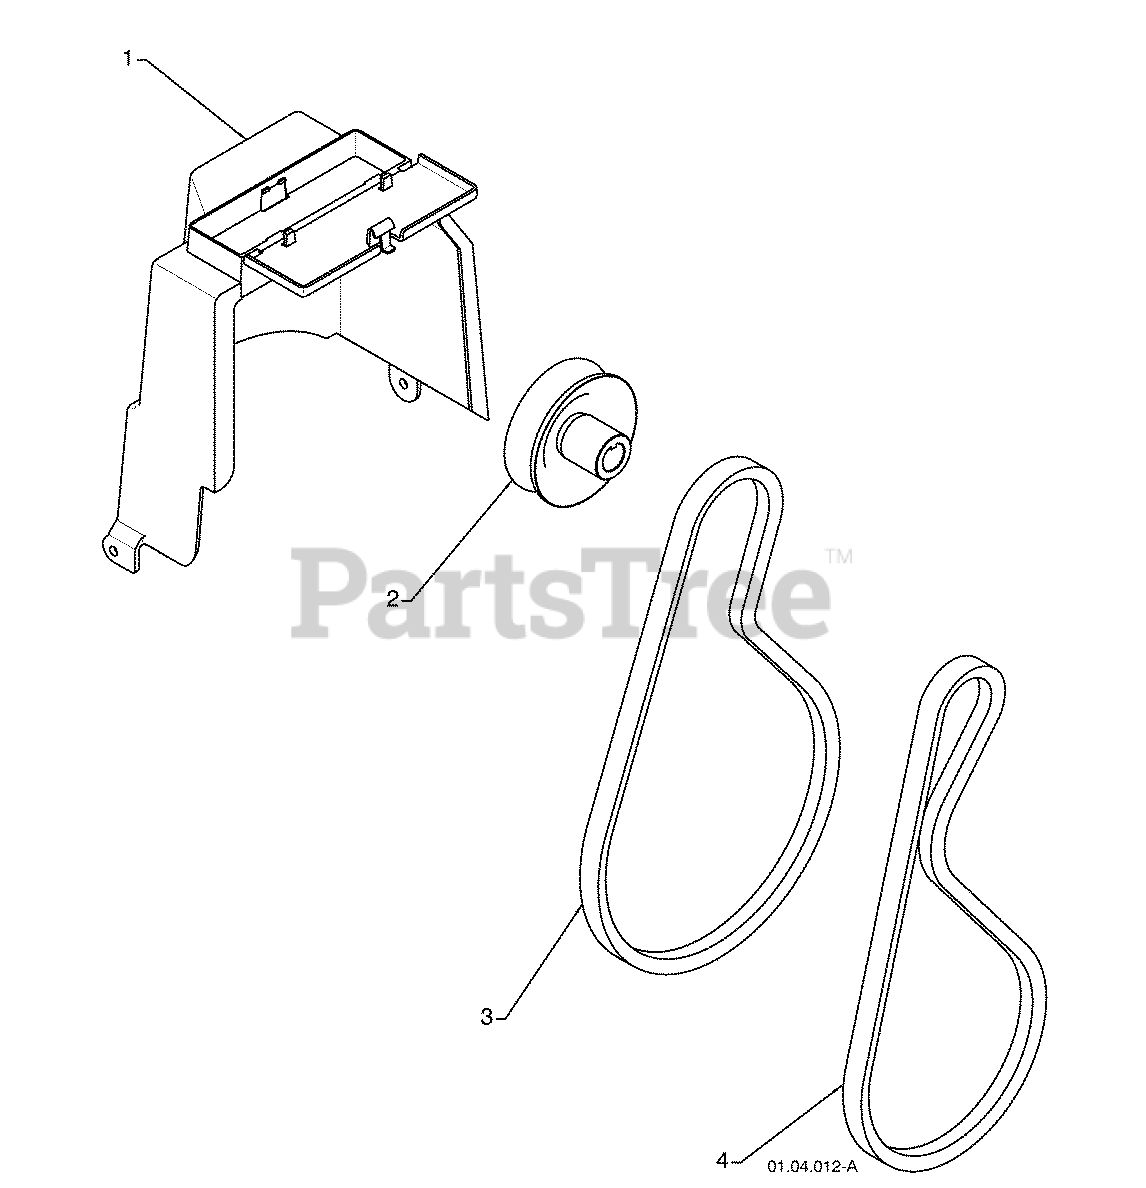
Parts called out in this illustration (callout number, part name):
1	COVER ASSEMBLY
2	PULLEY
3	TRACTION BELT
4	IMPELLER BELT
